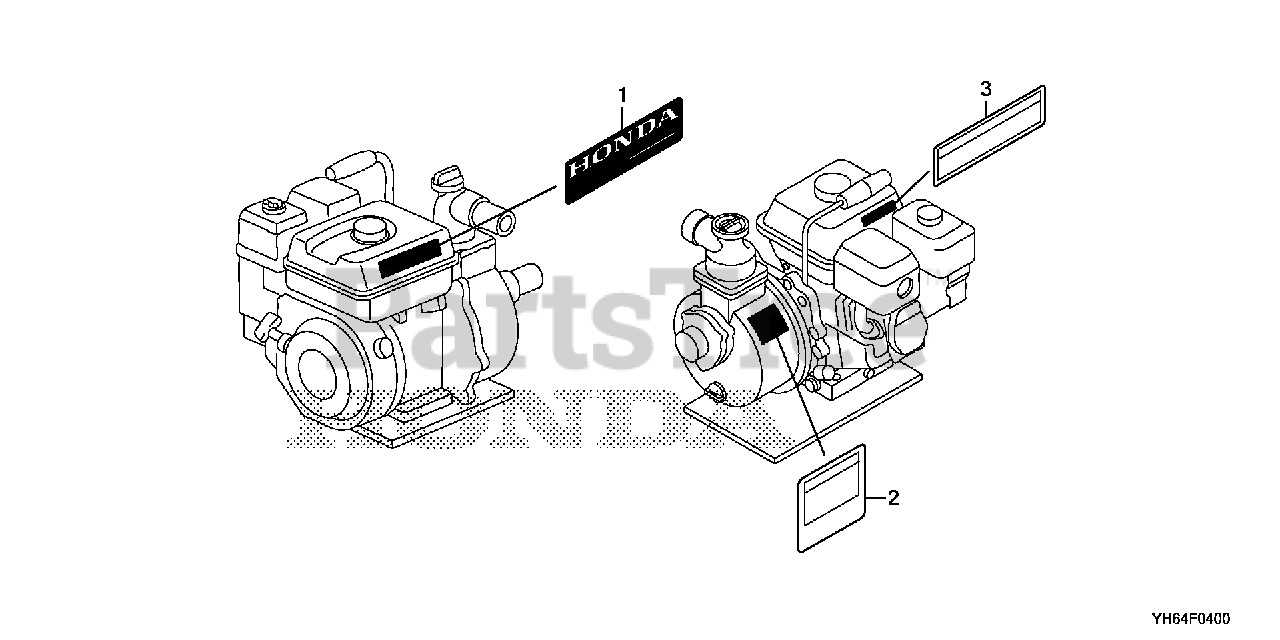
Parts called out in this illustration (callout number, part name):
1	MARK, EMBLEM (WH15XT)
2	LABEL, WARNING (ENGLISH)
3	LABEL, SPARK WARNING
